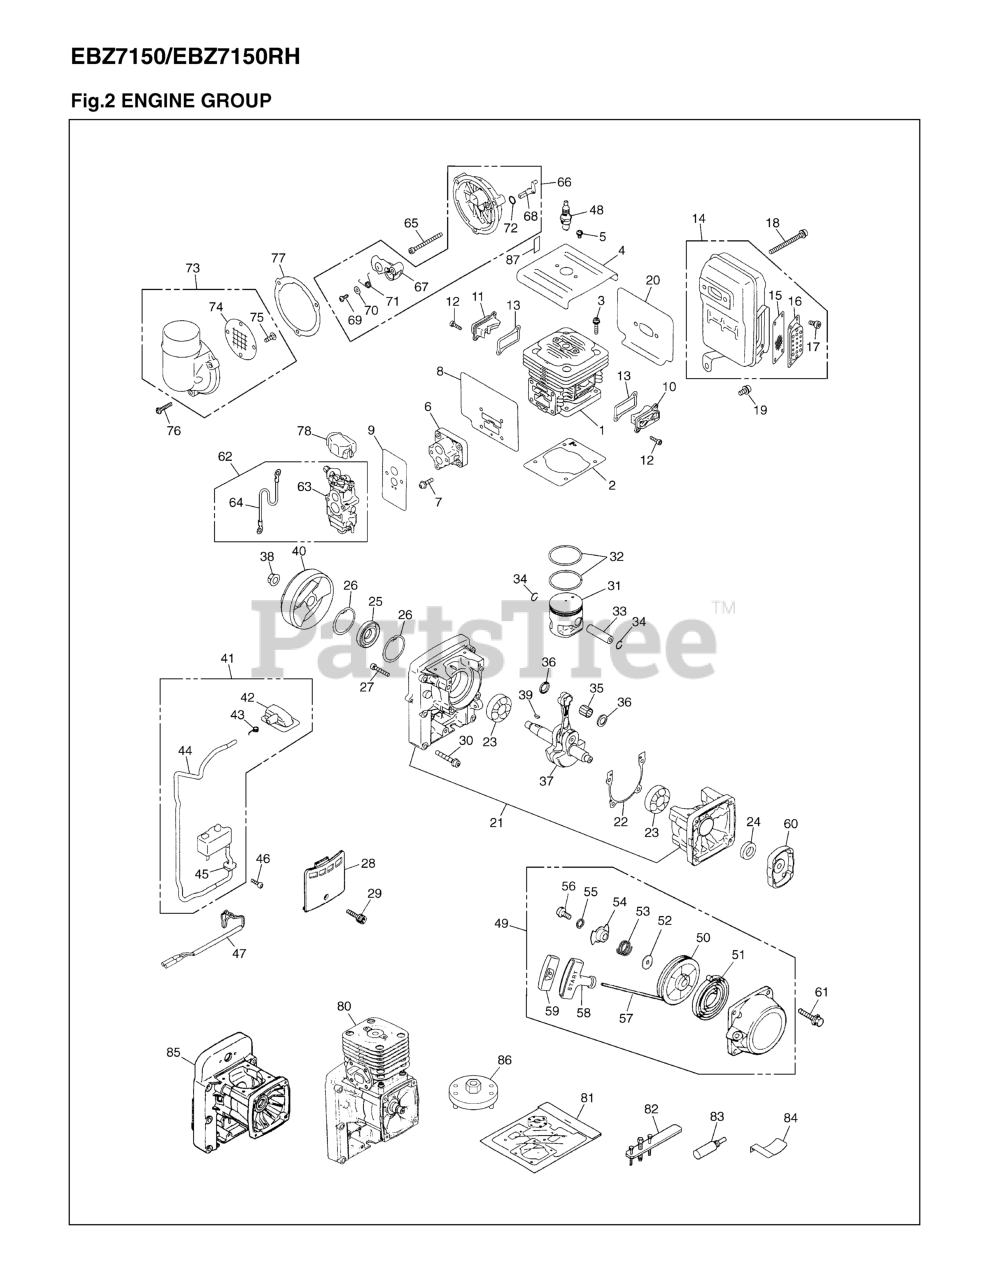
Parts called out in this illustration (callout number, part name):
1	CYLINDER
2	GASKET, BASE
3	BOLT
4	PLATE, CYL
5	SCREW TORX
6	INSULATOR
7	BOLT
8	GASKET, INSULATOR
9	GASKET, CARB.
10	COVER, TR (S)
11	COVER, TR (F)
12	BOLT TORX
13	GASKET, TR
14	MUFFLER ASSY
15	Arrester
17	Bolt
18	BOLT TORX
19	BOLT
20	GASKET
21	CRANKCASE-CASE
22	GASKET, CASE
23	BEARING
24	SEAL
25	SEAL
26	SNAP RING
27	BOLT
28	COVER
29	BOLT TORX
30	BOLT TORX
31	PISTON
32	RING, PISTON
33	PIN
34	SNAP RING
35	BEARING
36	WASHER
37	CRANKSHAFT-C
38	NUT, M10
39	KEY
40	ROTOR
41	COIL ASSY
42	CAP
43	SPRING
44	TUBE
45	GROMMET
46	BOLT TORX
47	CORD-C
48	USE T110873110
49	RECOIL ASSY (RPLS -7511)
50	REEL (REPLACES -75C1)
51	SPRING
52	WASHER (REPLACES -75M0)
53	SPRING, FRICTION (RPLS. -75L1)
54	PLATE, FRICTION (RPLS. -75K1)
55	WASHER (REPLACES -75W0)
56	SCREW
57	ROPE
58	KNOB
59	COVER KNOB
60	PULLEY (RPLS 848-H00-7520)
61	BOLT, TORX
62	CARBURETOR SET
63	CARBURETOR ASSY
64	Cord
65	BOLT
66	CHOKE CUP ASSY
67	PLATE, CHOKE
68	LEVER
69	SCREW
70	WASHER
71	SPRING
72	O-RING
73	COVER ASSY. (REPLACES -8340)
74	SCREEN
75	SCREW
76	SCREW
77	GASKET,CUP
78	COVER
80	SHORT BLOCK
81	GASKET KIT
82	PULLER ASSY
83	STOPPER (TOOL)
84	GAUGE
85	CRANKCASE-A
86	PULLER
87	LABEL, CHOKE
